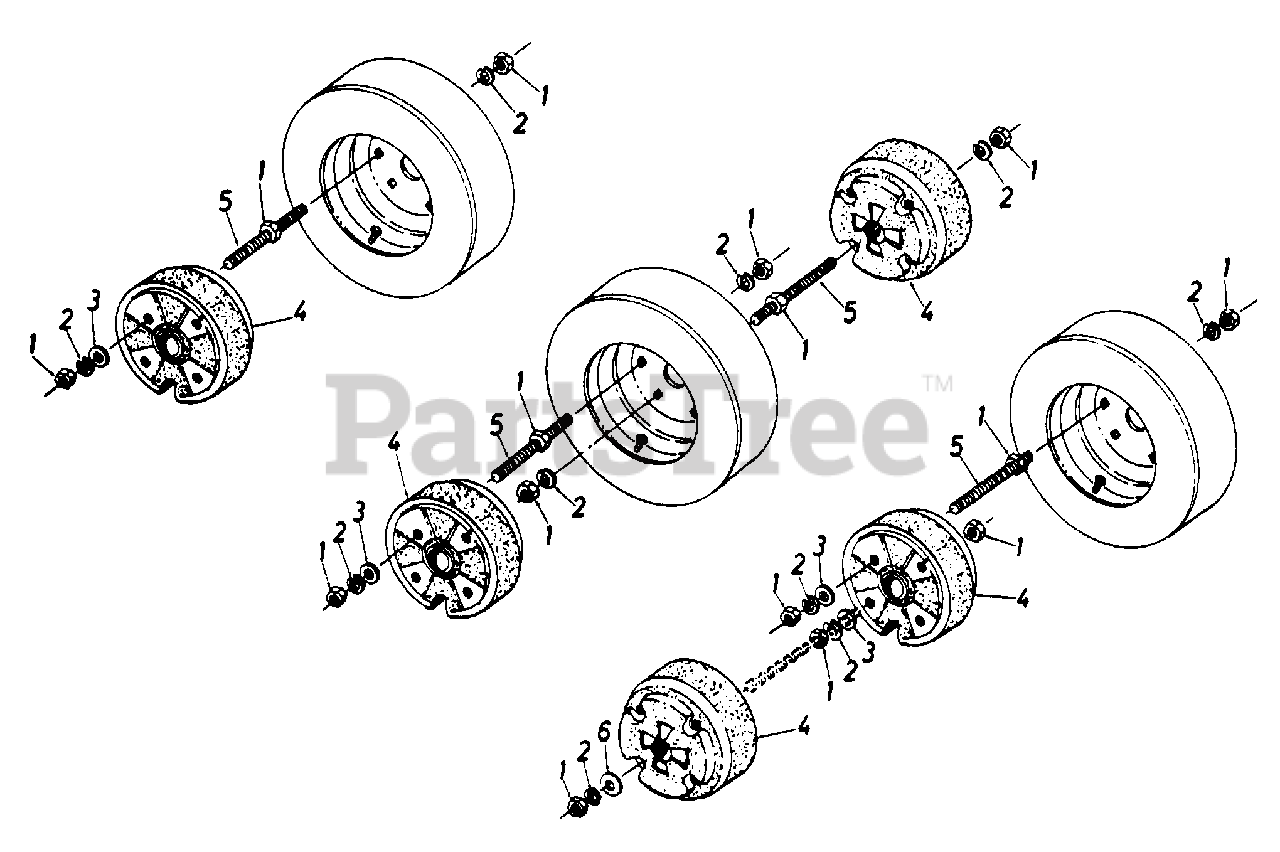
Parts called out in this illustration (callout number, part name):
1	Hex Nut 1/2-13 Thd.
2	Lock Washer 1/2" I.D.
3	FlatWasher.53" I.D. x.93" O.D.
4	Wheel Weight
5	Rod Threaded 1/2-13 x 9.50 Lg.
6	Fl.-Wash. .50" I.D. x 2.00" O.D.
